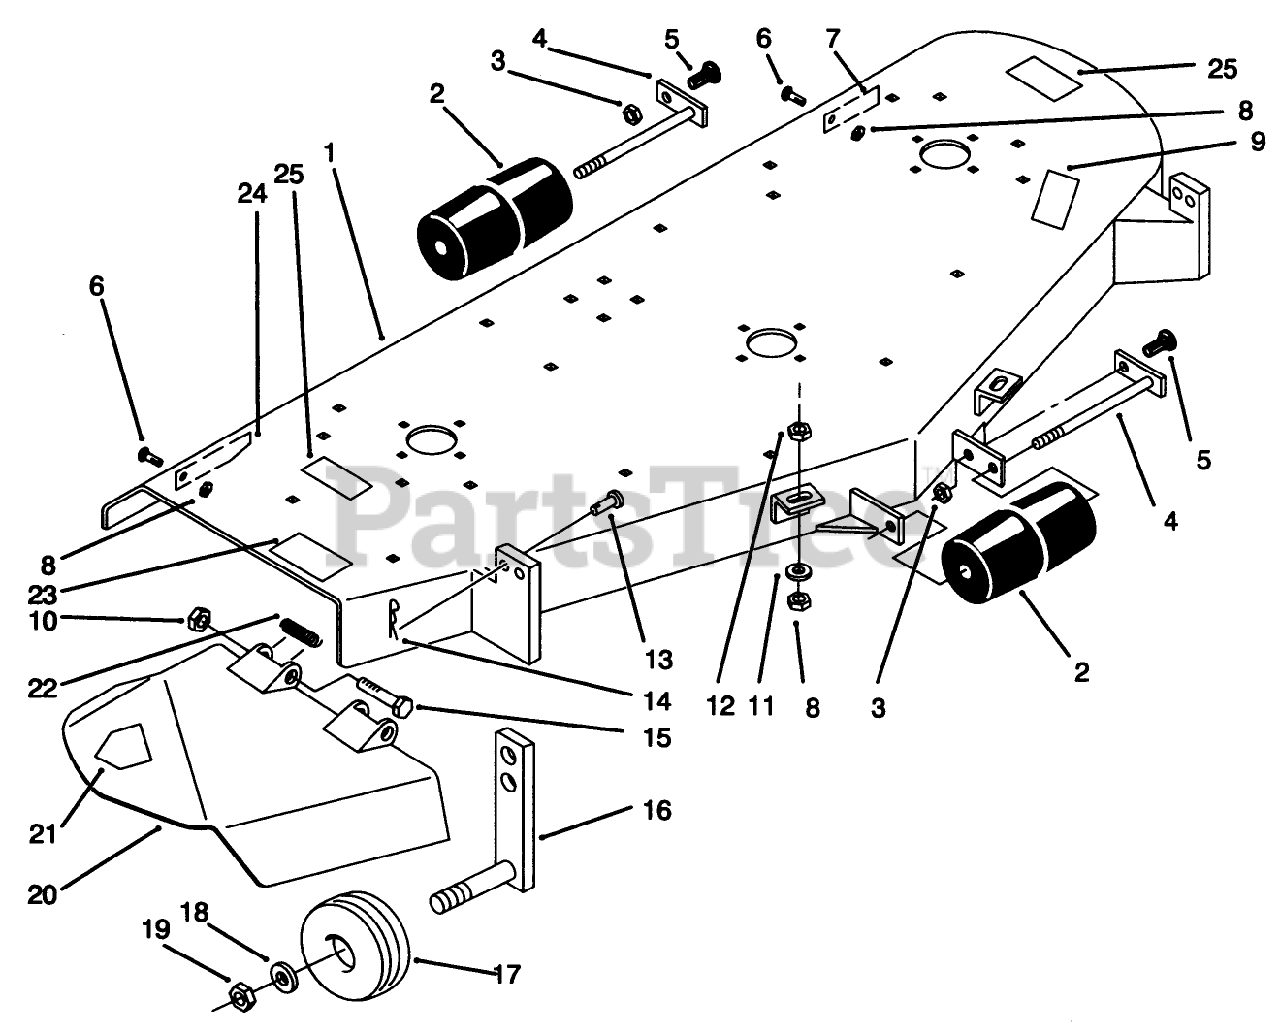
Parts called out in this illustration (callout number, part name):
1	60" Deck & Safety Decal Assy. (Incl. Ref. #23 & 25)
2	ROLLER-ANTI SCALP
3	NUT-LOCK, NI
4	ROLLER-SHAFT
5	BOLT-CARR
6	BOLT-CARR
7	Plate-Wear, L.H.
8	NUT-LOCK, NI
9	DECAL - WHEEL ADJUSTMENT
11	WASHER-FLAT
12	NUT-FLANGE
13	PIN-CLEVIS 3/8 X 1
14	PIN-HAIR
15	SCREW-HH
16	GAGE-WHEEL
17	WHEEL-GAGE
18	WASHER-FLAT
19	NUT-LOCK, NI
20	Chute & Safety Decal Assy. (Incl. Ref. #21)
21	DECAL-DANGER
22	SPRING
23	DECAL-DANGER
24	Wear Plate RH
25	DECAL-DANGER, THROWN OBJECT
